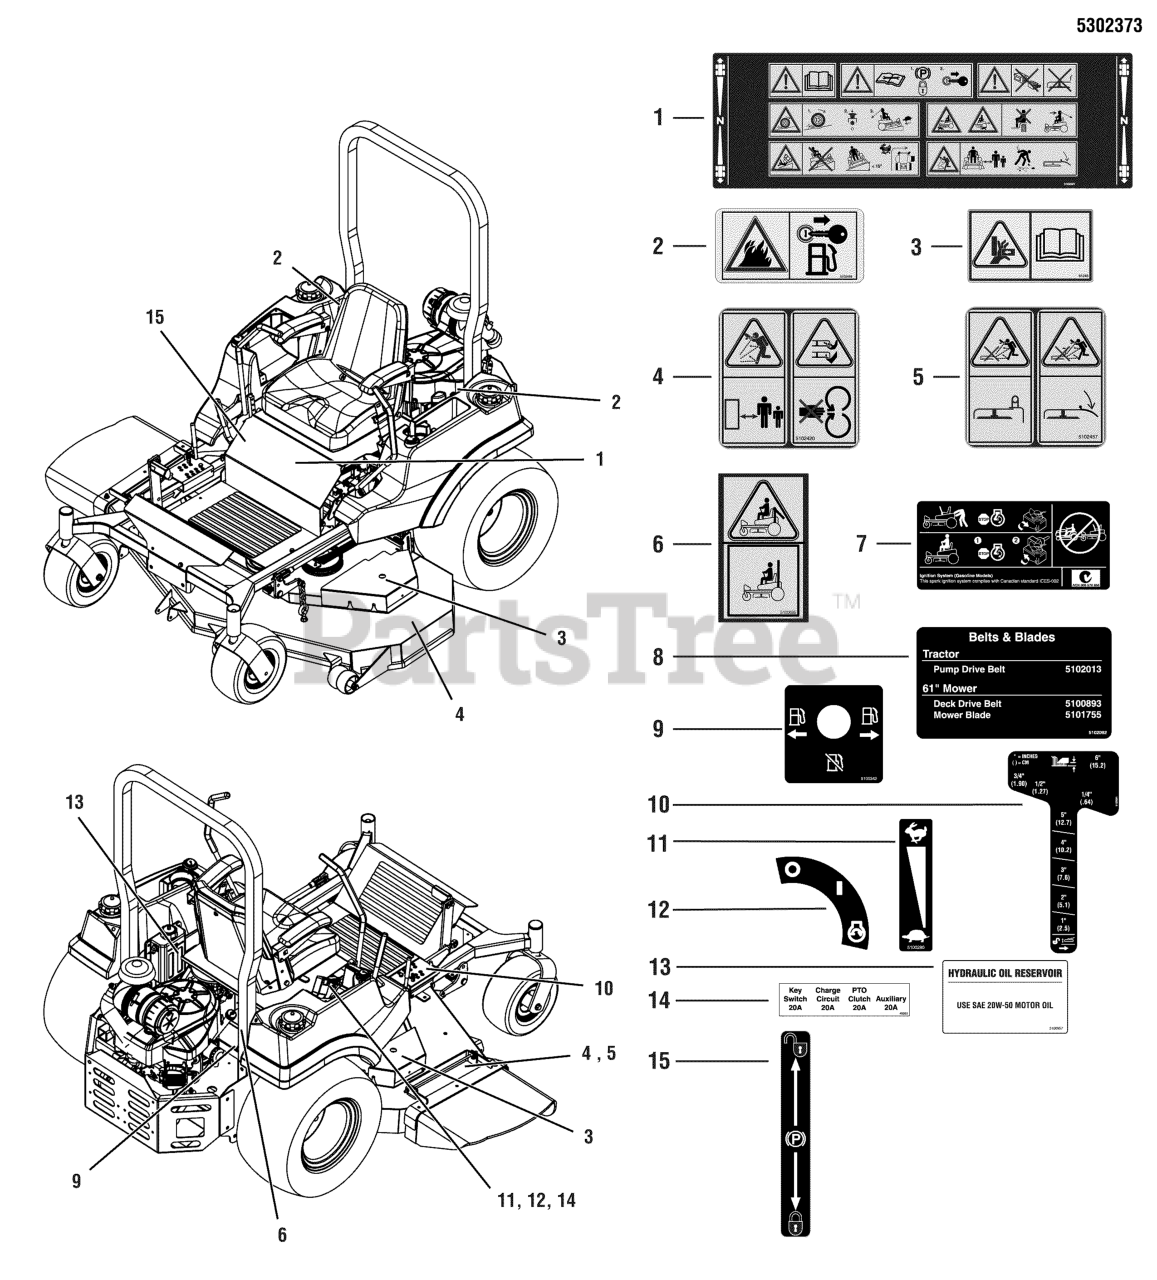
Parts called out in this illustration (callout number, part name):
1	DECAL, MAIN SAFETY, ANSI CE
2	DECAL, FIRE ANSI EXPORT
3	DECAL, PINCH POINT, CE
4	DECAL, DANGER, MOWER DECK, ANSI EXP
5	DECAL, DANGER DISCHARGE ANSI EXPORT
6	DECAL, WARNING, ROLL BAR, CE
7	DECAL, TRANSAXLE RELEASE, S200XT
8	DECAL, BELT & BLADE, S200XT
9	DECAL, FUEL VALVE
10	DECAL, DECK HEIGHT, 1-1/2 TO 6, S200XT
11	DECAL, THROTTLE CONTROL
12	DECAL, IGNITION SWITCH
13	DECAL, HYDRAULIC OIL, SAE 20W50
14	DECAL, FUSE LOCATION
15	DECAL, PARKING BRAKE SYMBOLS
